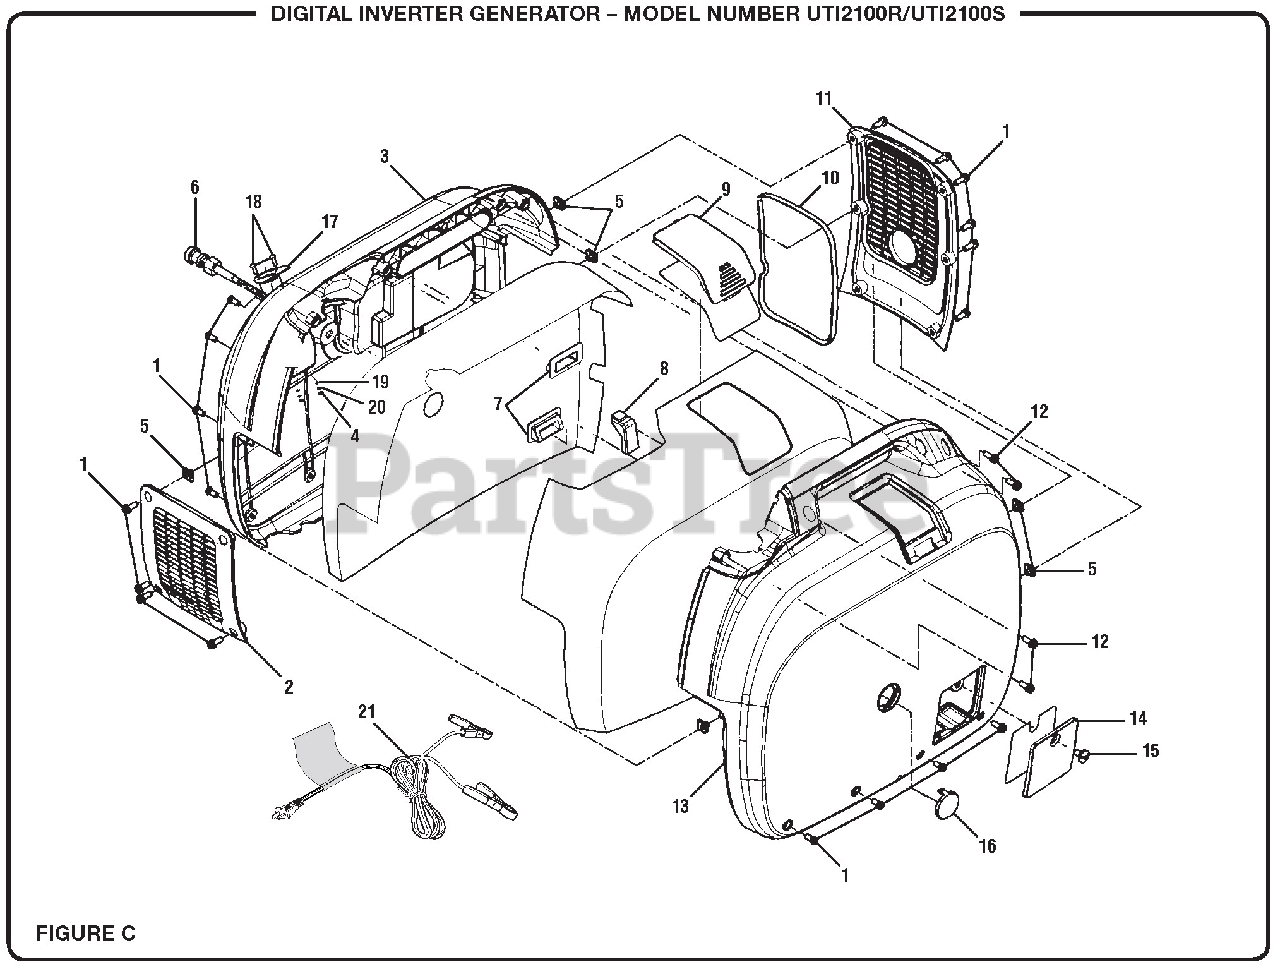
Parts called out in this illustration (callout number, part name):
1	Screw (M5 x 12 mm)
2	Air Intake Cover
3	Right Panel w/ Sound Foam (UTi2100R)
4	Hex Nut (M3)
5	U-Clip w/ Nut (M5)
9	Spark Plug Cover (UTi2100R)
11	Muffler Outer Cover
12	Screw (M5 x 15 mm)
13	Left Panel w/ Sound Foam (UTi2100R)
14	Oil Fill Cover (UTi2100R)
15	Bolt (M6 x 13 mm)
16	Fuel Drain Cover (UTi2100R)
17	Recoil Starter Bracket
18	Screw (M3 x 10 mm)
20	Spring Washer (M3)
21	DC Charging Cable
